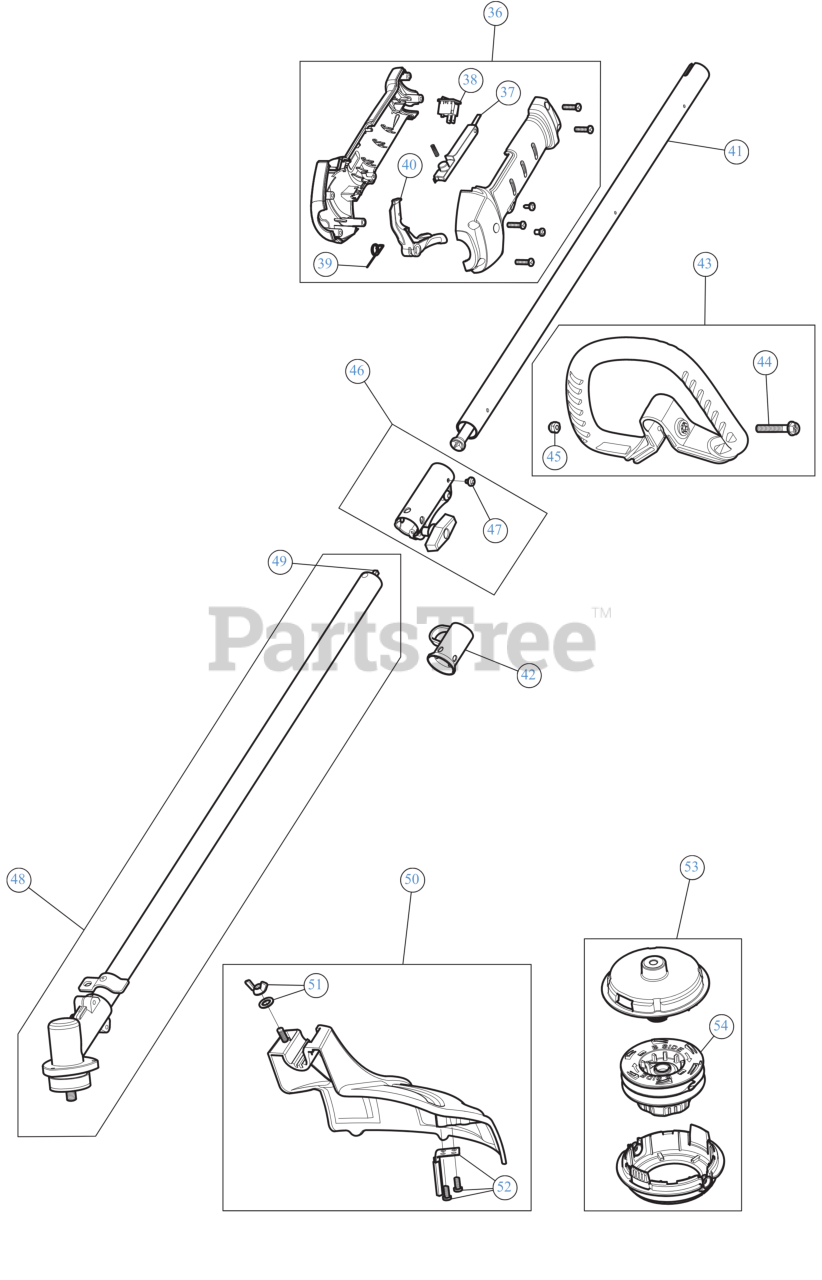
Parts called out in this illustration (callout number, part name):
36	THROTTLE GRIP ASSEMBLY
37	THROTTLE LVR LKOUT
38	SW, MOMENTARY ON/O
39	SPRING TRIG
40	THROTTLE TRIGGER
41	BOOM ASSEMBLY UPR
42	HANGER
43	HANDLE ASSEMBLY
44	BOLT 1/4-20X1 1/2
45	NUT 1/4-20 NYLOC
46	COUPLER ASSEMBLY
47	SCREW, 10-32X.250 TA
48	BOOM (W/GEARBOX)
49	LOWER DRIVE SHAFT
50	GUARD/BLADE ASM
51	BLADE GUARD MOUNTING HARDWARE
52	BLADE ASSEMBLY W/HDW
53	COMPLETE HEAD ASSEMBLY
54	BUMP KNOB
